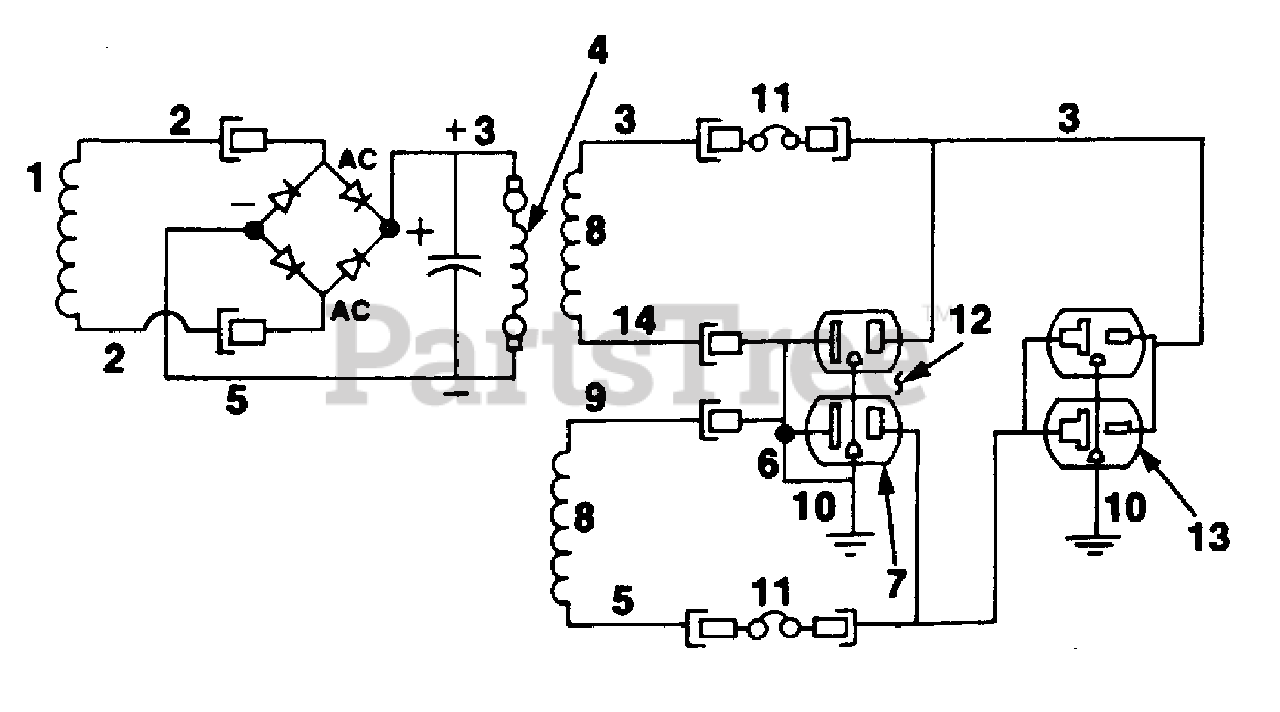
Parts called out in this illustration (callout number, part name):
1	QUAD COIL
2	YELLOW
3	RED
4	FIELD COIL
5	BLACK
6	GREEN
9	WHITE
10	GROUND
11	CIRCUIT BREAKER
12	TAB BROKEN
14	BROWN
